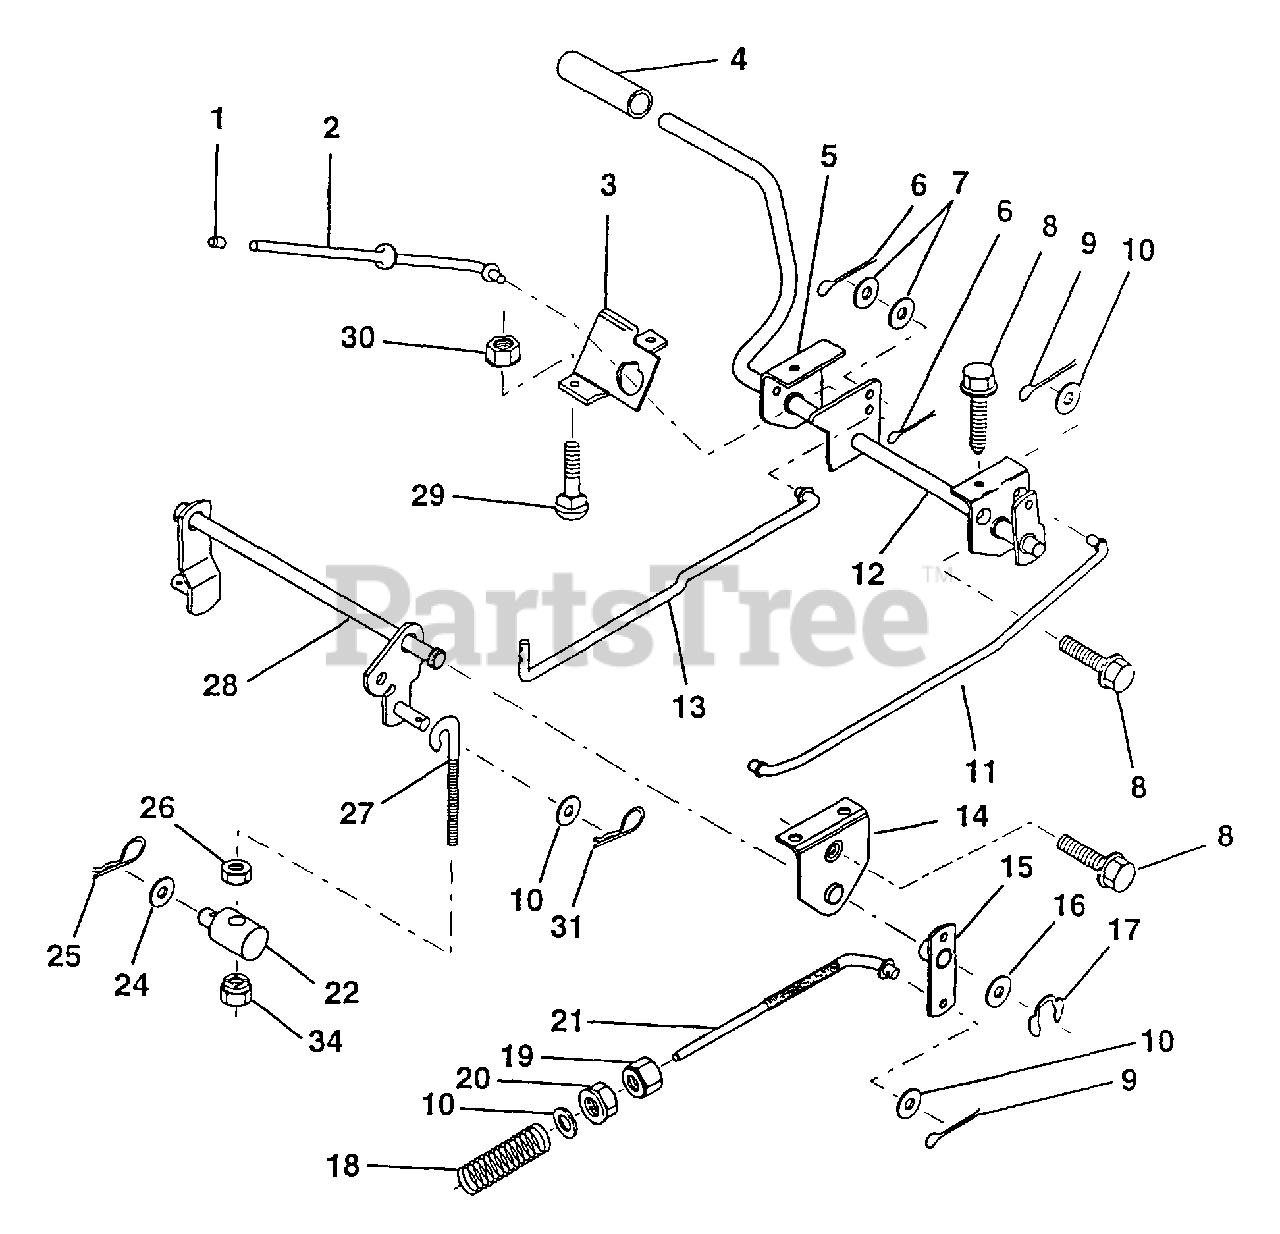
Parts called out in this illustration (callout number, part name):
1	Cap, Plunger
2	Rod, Parking Brake
3	Bracket, Parking Brake
4	Cover, Pedal
5	Bracket, Clutch/Brake Pedal, L.H.
6	Pin, Cotter 3/32 x 3/4
7	Washer 13/32 x 5/8 x 16 Ga.
8	Screw, Hex, Thd. Roll. 5/16-18 x 1/2
9	Pin, Cotter 1/8 x 3/4
10	Washer 13/32 x 13/16 x 16 Ga.
11	Rod, Brake Front
12	Assembly, Clutch/Brake Pedal
13	Rod, Clutch
14	Bracket, Lift, Shaft
15	Assembly, Brake, Pivot, Arm
16	Washer 25/32 x 1-1/8 x 16 Ga.
17	Ring, Klip
18	Spring, Brake Rod
19	Nut, Hex, Jam 3/8-16 UNC
20	Nut, Lock, Hex W/Ins. 3/8-16 UNC
21	Rod, Rear Brake
22	Trunnion, Lift
24	Washer 13/32 x 1-1/4 x 12 Ga.
25	Spring, Retainer
26	Nut, Centerlock 3/8-16 UNC
27	Link, Threaded
28	Assembly, Rear Mower Lift
29	Bolt, Carriage 5/16-18 UNC x 3/4
30	Nut, Keps 5/16-16 UNC
31	Retainer Spring
34	Nut, Crownlock 3/8-16 UNC
